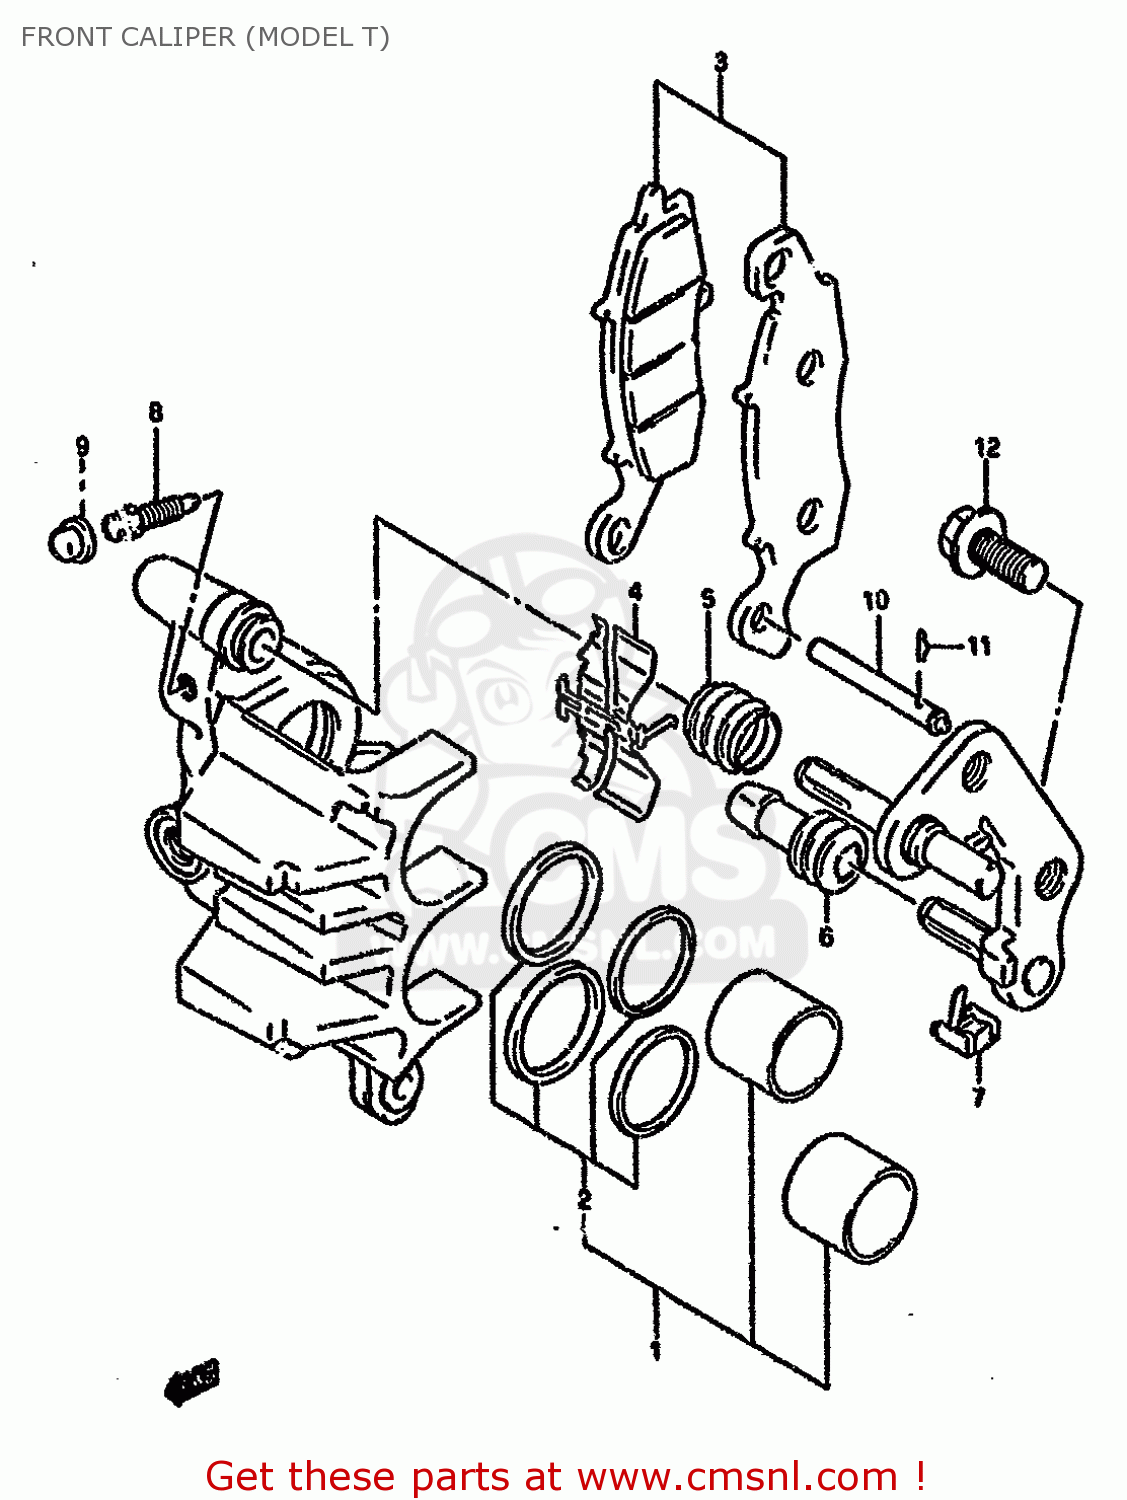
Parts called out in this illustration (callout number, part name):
1	PISTON SET
2	SEAL SET,PISTON
3	PAD SET (NAS)
4	SPRING,PAD,R
5	BOOT,AXLE
6	INSULATOR,AXLE
7	GUIDE,PAD
8	BLEEDER
9	CAP,BLEEDER PLUG
10	PIN,PAD
11	CLIP,PAD PIN
12	BOLT
13	CAP,BREATHER
14	BOLT
